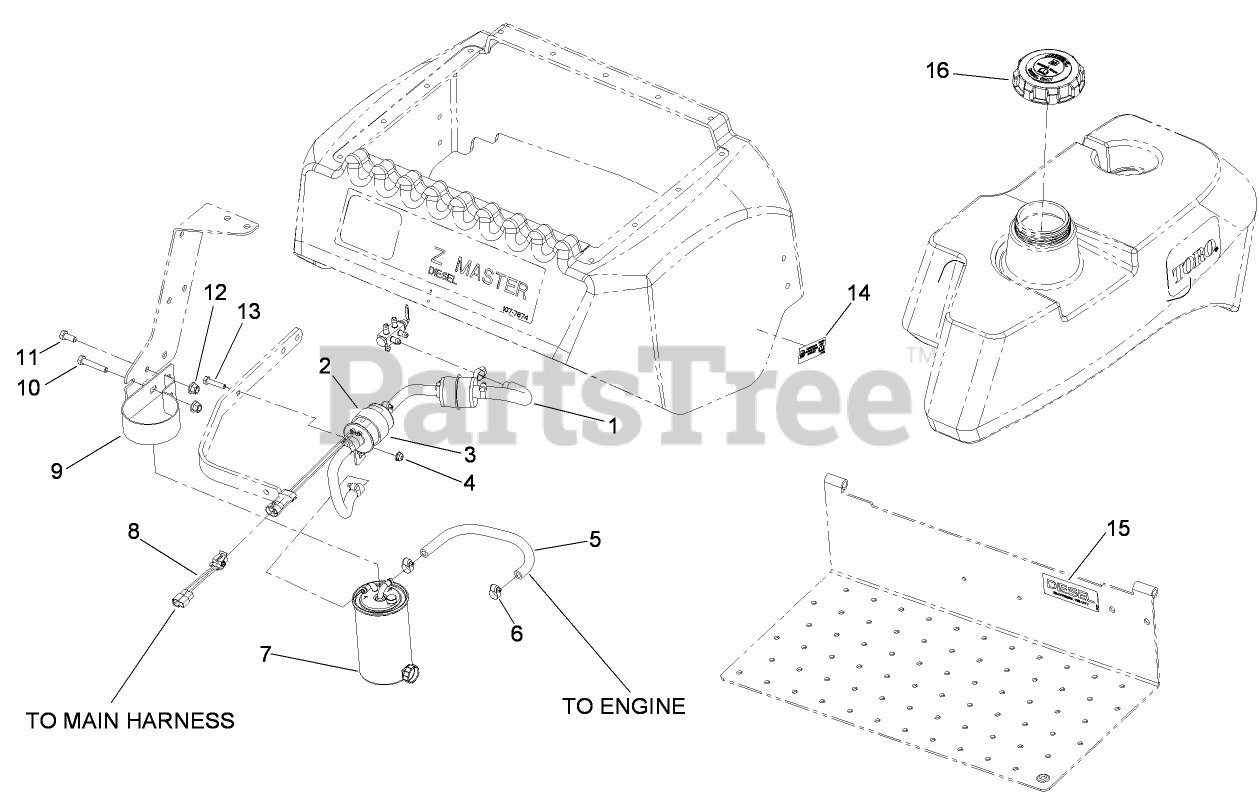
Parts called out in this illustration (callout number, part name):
1	CONDUIT-FUEL LINE
2	FUEL HOSES, FILTER AND PUMP ASM (Not serviced separately)
3	BRACKET-PUMP, FUEL
4	NUT-HF
5	HOSE-FUEL
6	CLAMP-WORM
7	ELEMENT-FILTER, FUEL/WATER
8	HARNESS-WIRE
9	BRACKET-FILTER, FUEL
10	SCREW-HH
11	SCREW-HH
12	NUT-LOCK, NI
13	SCREW-HH
14	DECAL-LOW SULFUR
15	DECAL-DIESEL, BIO-READY
16	BIODIESEL CAP ASM
